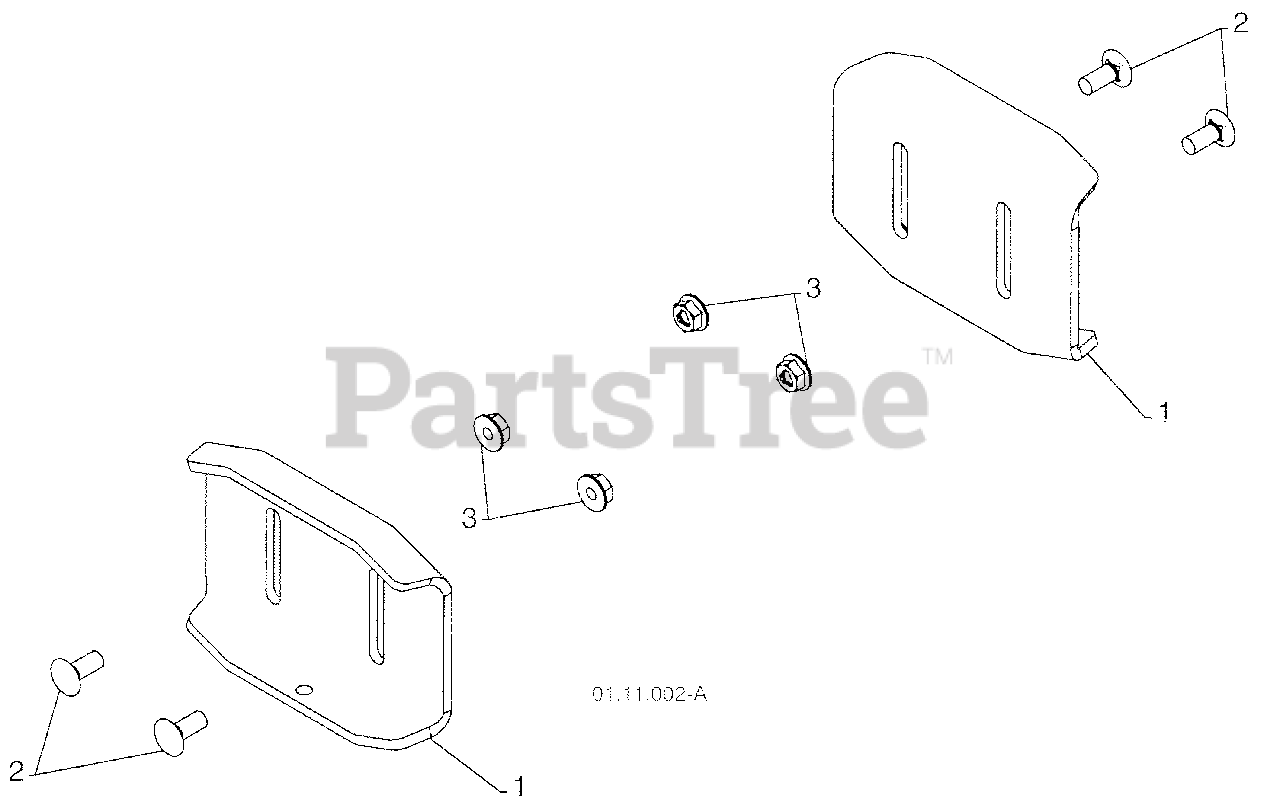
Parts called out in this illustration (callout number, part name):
1	SKID PLATE
2	CARRIAGE BOLT 5/16-18 X .750
3	NUT 5/16-18
